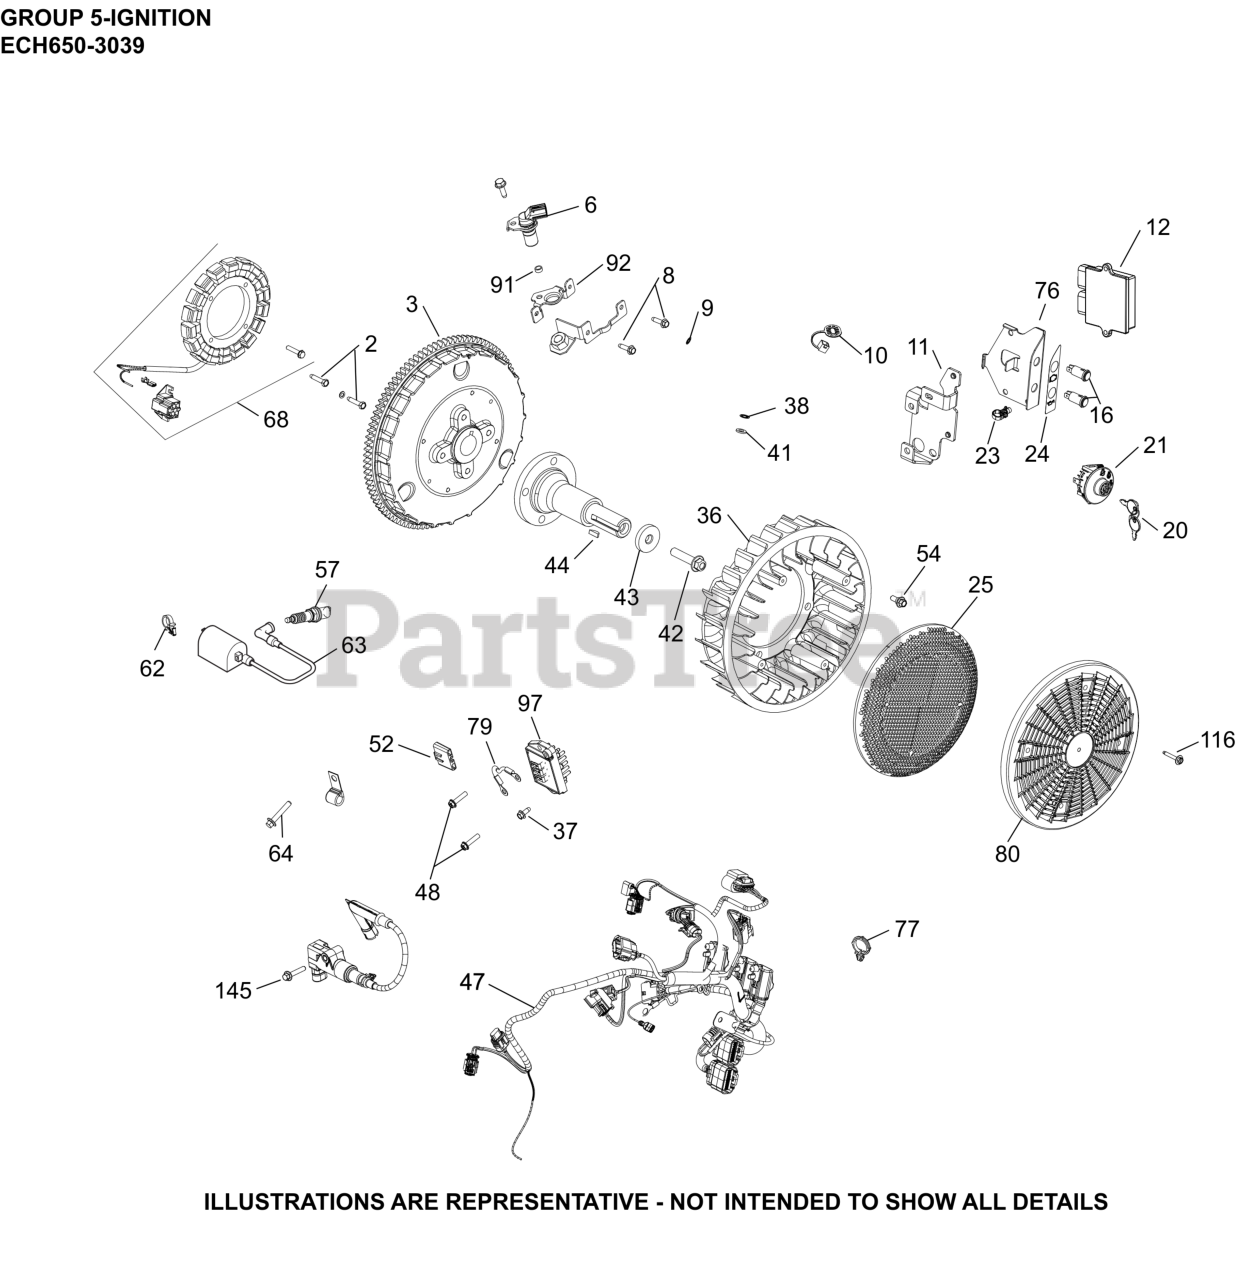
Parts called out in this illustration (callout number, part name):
2	SCREW, THREAD FORMING
3	FLYWHEEL, ASSEMBLY-(#24025115S)
6	SENSOR, SPEED
8	SCREW, THREAD FORMING
9	WASHER, INT TOOTH LOCK #10
10	CAP, CONNECTOR
11	BRACKET, ECU
16	LIGHT, INDICATOR
20	KEY, SET OF 2
21	KIT, KEY SWITCH (SNAP-IN)
23	TIE, WIRE
24	DECAL, WARNING LIGHT
25	KIT GRASS SCREEN
36	FAN-USE 24 755 253-S
37	SCREW, THREAD FORMING
38	WASHER, INT TOOTH LOCK 1/4"
41	WASHER, FLAT 1/4" (O.D. 1/2")
44	KEY, 3/16" X 5/8"
47	HARNESS, WIRING ASSEMBLY
48	SCREW, HEX FLANGE HI-LO
52	CONNECTOR
54	BOLT, SHOULDER
57	SPARK PLUG, RFI
63	COIL, IGNITION - EFI (RFI/EMC)
68	KIT, 25 AMP STATOR ASSY.
76	BRACKET, WARNING LIGHT
77	RETAINER, WIRE HARNESS
80	SCREEN, GRASS
92	BRACKET, SENSOR
97	REGULATOR, RECT (20-30AMP, FW W/OVP)
116	SCREW, FLG SEMS M4x.7x25
NI	MODULE, ECU ECH650
NI	SCREW, HEX FLANGE
NI	WASHER, FLAT
